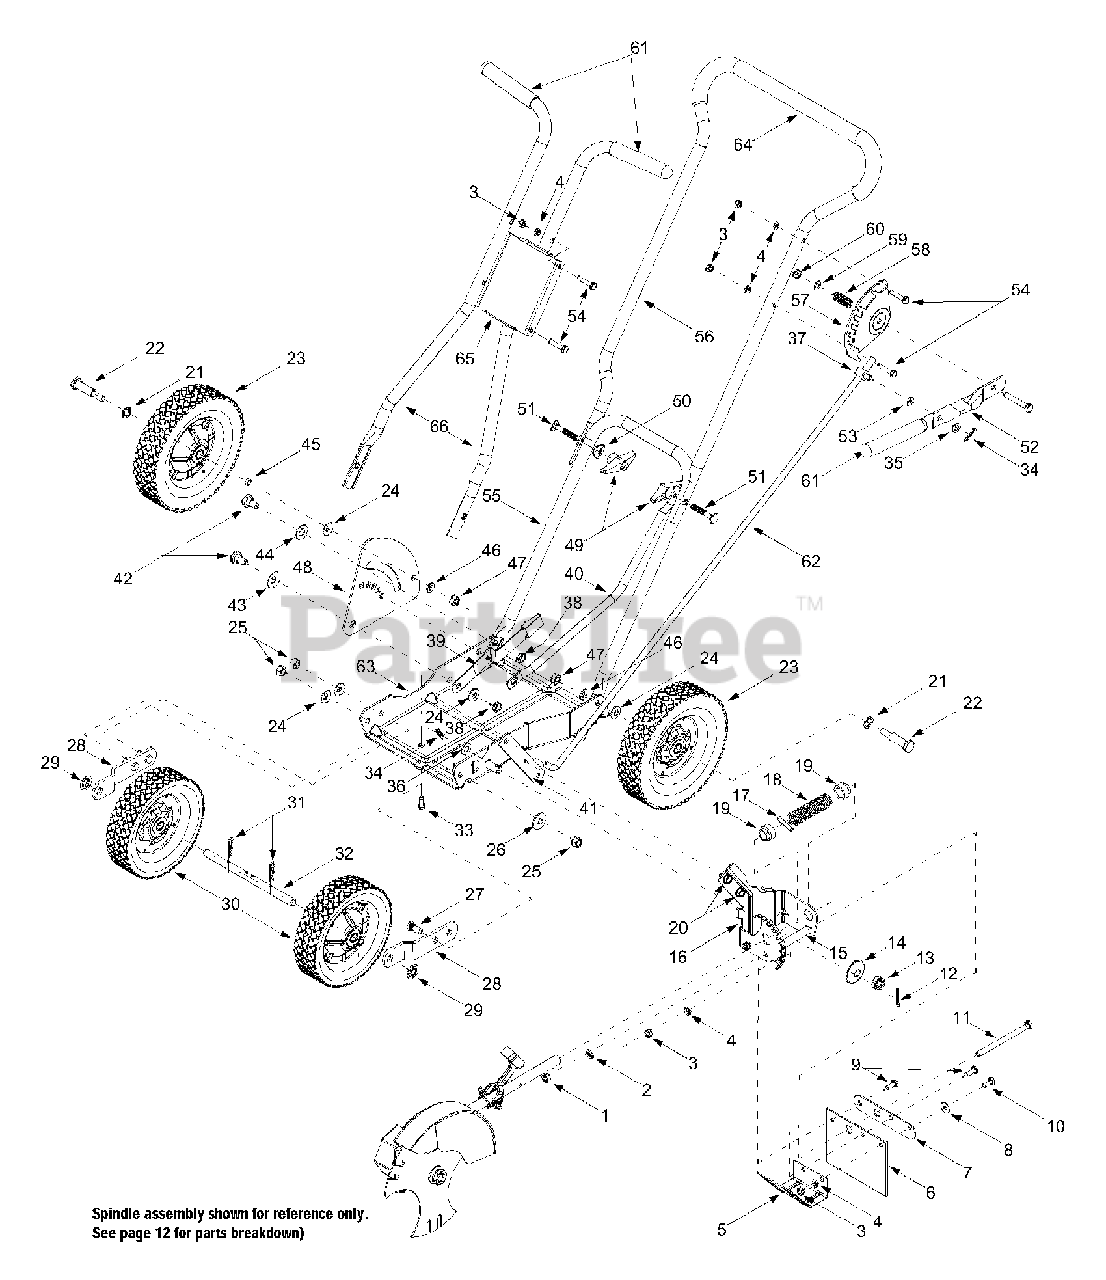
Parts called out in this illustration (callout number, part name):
1	Hex Nut, 5/16-18
2	Lock Washer, 5/16
3	Hex Nut, 1/4-20
4	Lock Washer, 1/4
9	Hex Screw w/ Nose, 1/4-20 x .85
10	Hex Screw, 1/4-20 x .62
11	Hex Screw, 5/16-18 x 4.5
12	Cotter Pin, 1/8 x 1.0
13	Slotted Hex Nut, 1/2-20
14	Sphere Washer, .531 x 1.6 x .045
15	Spacer, .38 x .50 x 3.75
18	Compression Spring
19	Shoulder Spacer, .635 x .620
20	Self-tapping Screw, 5/16-18 x .50
21	Wave Washer, .510 x .75 x .017
22	Shoulder Screw, .498 x 1.45
23	Wheel w/ Ball Bearing, 8 x 1.75
24	Spring Washer, .401 x .871 x .063
25	Hex Nut, 3/8-24
26	Bell Washer, .396 x 1.14 x .095
27	Round Head Bolt, 3/8-24 x .89
30	Wheel w/ Ball Bearing, 7 x 1.75
31	Internal Cotter Pin, .08 x 1.42
32	Front Axle, .50 x 7.98
33	Self-tapping Screw, 3/8-16 x 1.0
34	Internal Cotter Pin, .072 x 1.0
35	Flat Washer, .330 x .630 x .0635
36	Flat Washer, .406 x .810 x .051
37	Adjustment Ferrule
38	Center Lock Nut, 3/8-24
39	Curb Adjustment Lever Assembly
43	Bell Washer, .51 x 1.14 x .040
44	Flat Washer, .51 x 1.0 x .060
45	Spacer, .376 x .625 x .22
46	Lock Washer, 3/8
47	Hex Nut, 3/8-16
50	Saddle Washer, .320 x .93
51	Carriage Bolt 5/16-18 x .75
53	Spring Washer, .317 x .625 x .099
54	Hex Cap Screw, 5/16-18 x 2.0
58	Compression Spring, .55 x 1.37
59	Flat Washer, .344 x .62 x .030
60	Hex Lock Nut, 5/16-18
61	Foam Grip
62	Clutch Rod, 3/8 x 33.5
